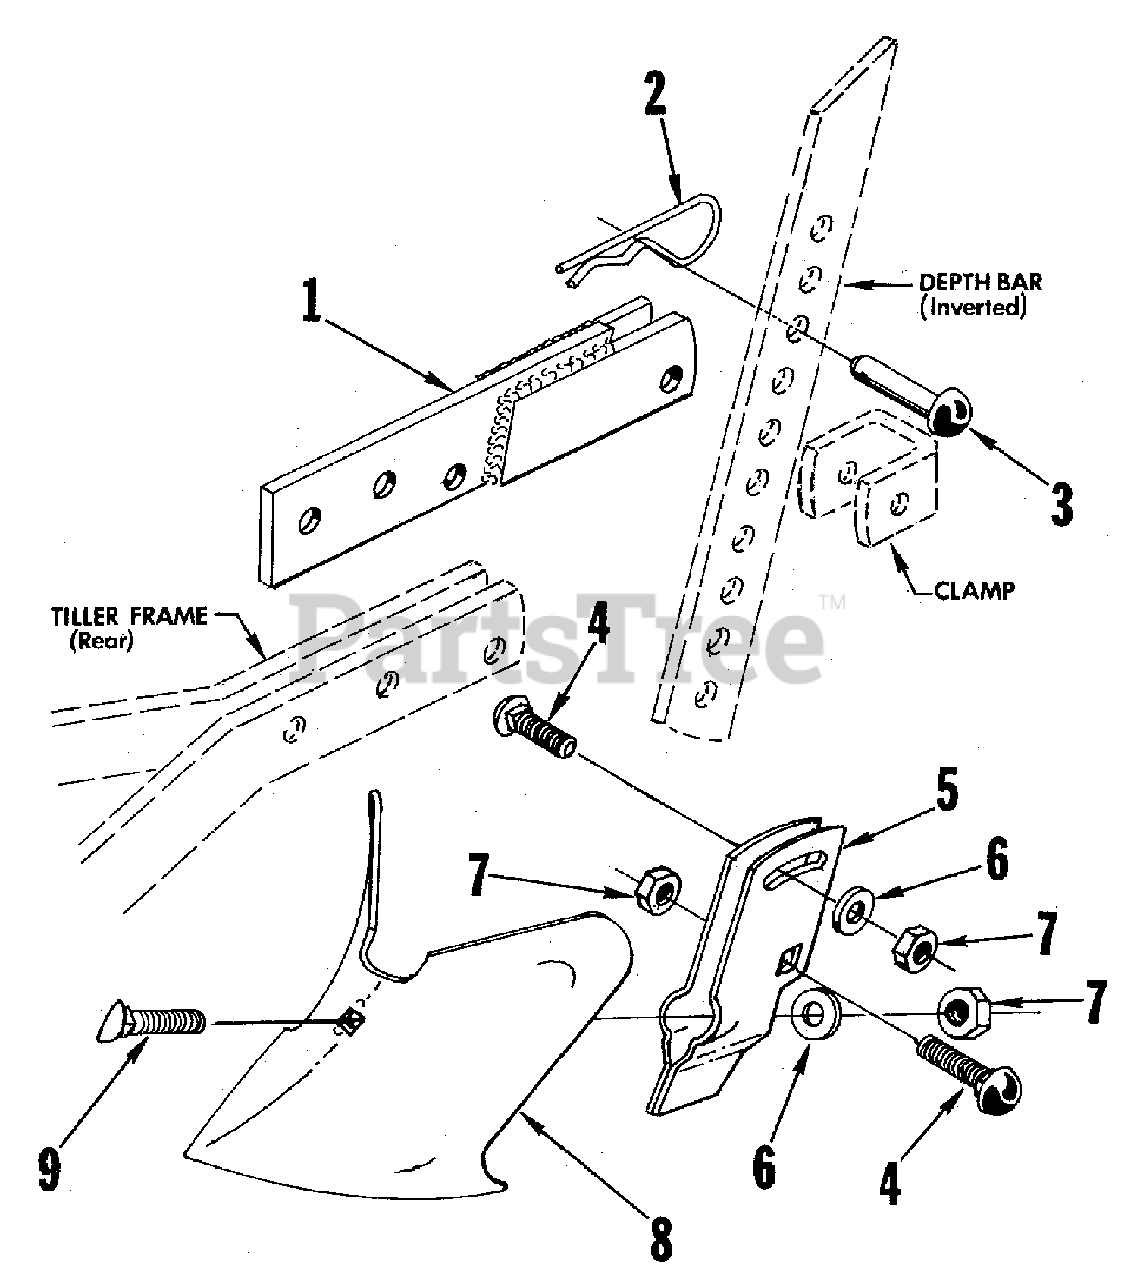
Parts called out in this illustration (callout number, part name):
1	SUPPORT ASSEMBLY, Extension
2	CLIP, Spring
4	BOLT, Carriage, 3/8-16 x 1-1/4"
5	TOOL HOLDER ASSEMBLY
6	WASHER, Flat, 3/8"
7	NUT, Hex, Full, 3/8-16
8	FURROW OPENER, 8"
9	BOLT, Plow, 3/8-16 x 1-3/4
